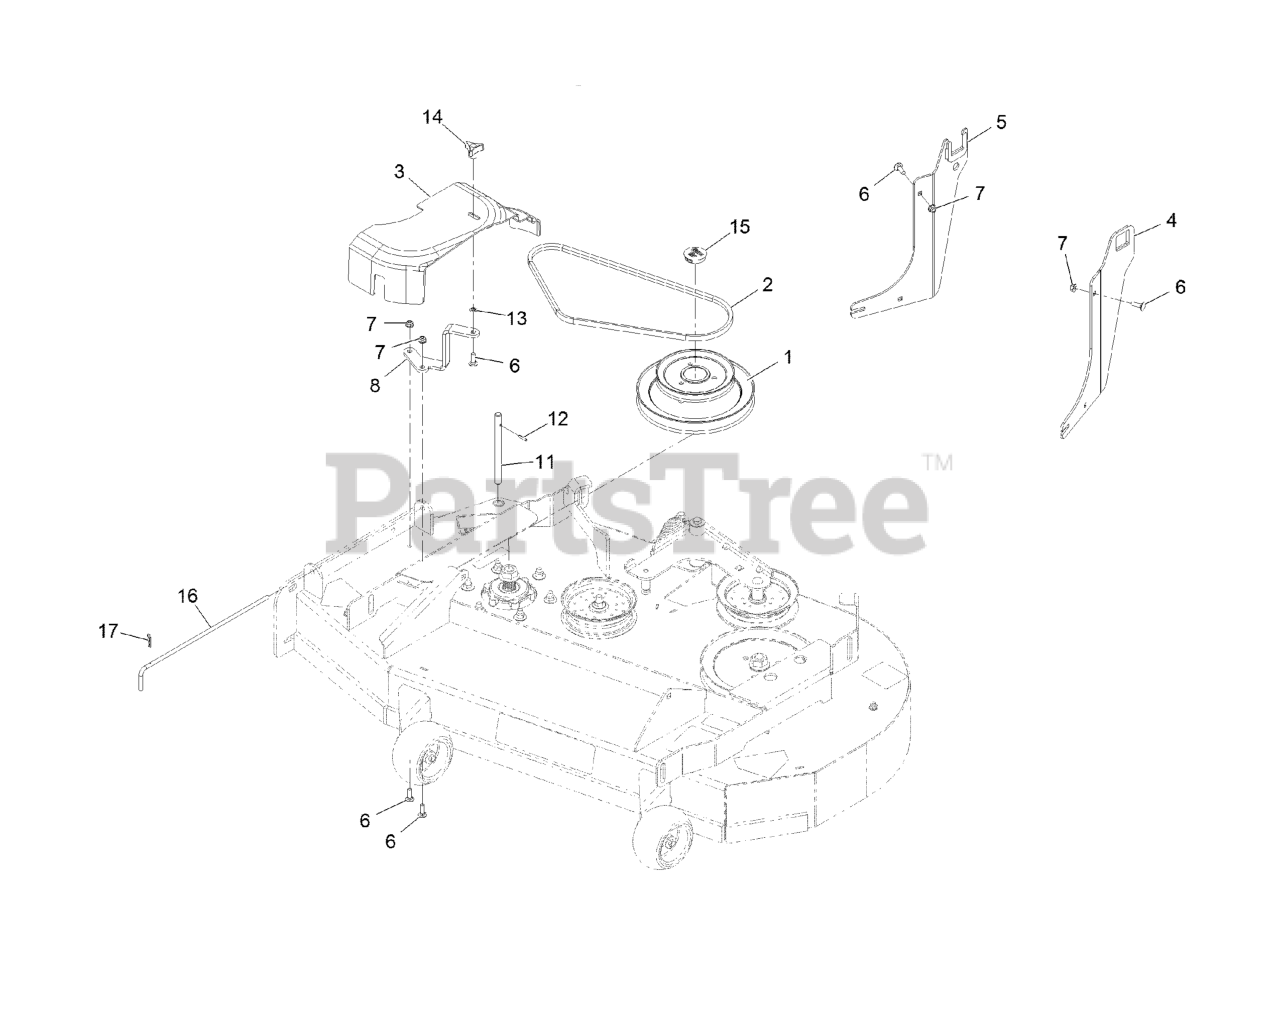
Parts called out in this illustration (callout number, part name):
1	JACKSHAFT-UV DRIVE, 44 SP
2	BELT, BLOWER DRIVE 72
3	COVER-BELT, UV 44
4	BRACKET ASM, LH
5	BRACKET ASM, RH
6	BOLT-CARR
7	NUT-HF, NI
8	BRACKET-BELT COVER 44
11	SHAFT-CATCHER, GRASS
12	PIN-ROLL
13	RING-RETAINING, BOLT
14	KNOB-3 PRONG
15	PLUG, BLACK NYLON 1.75
16	PIN,CHUTE PIVOT
17	PIN-COTTER
